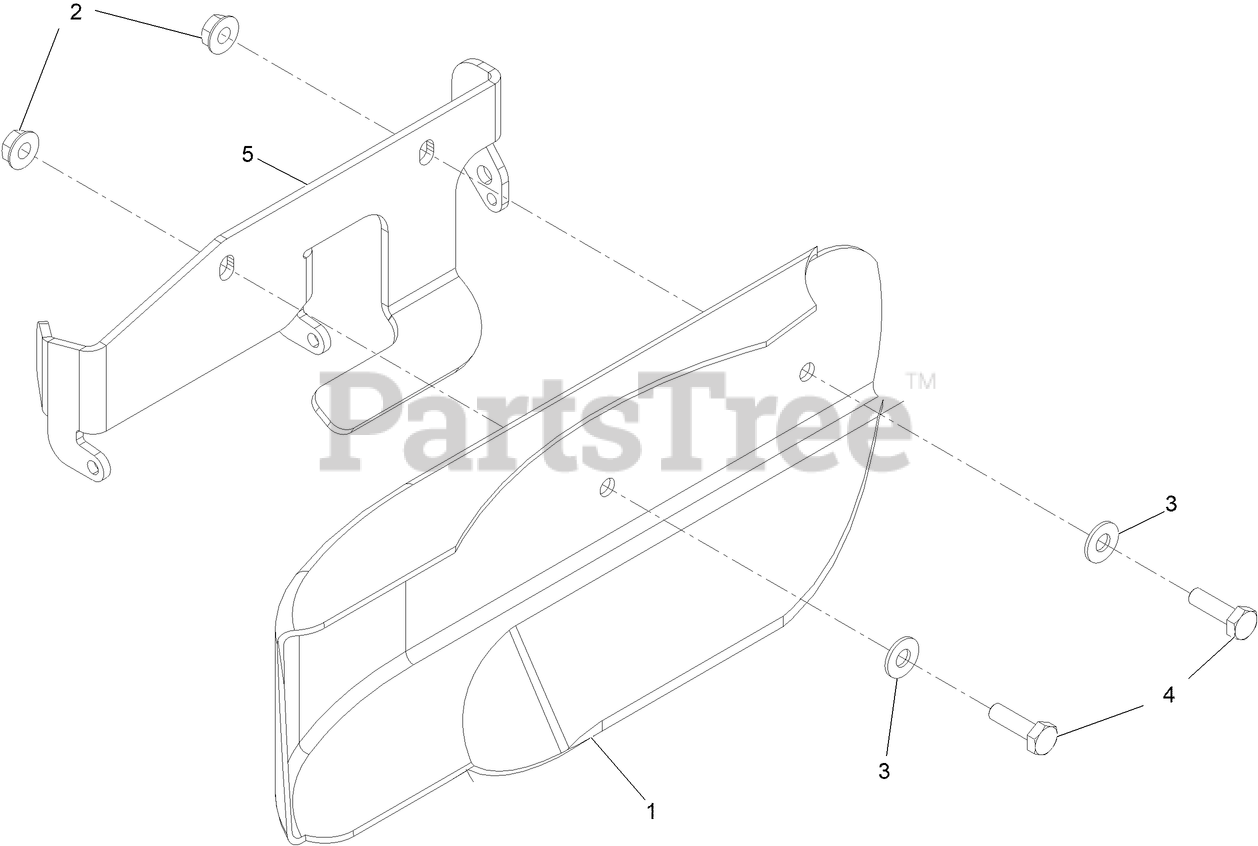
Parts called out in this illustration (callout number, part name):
1	DEFLECTOR-SIDE
2	BRACKET-DEFLECTOR, SIDE
3	WASHER-FLAT
4	SCREW-HH
5	NUT-HF
